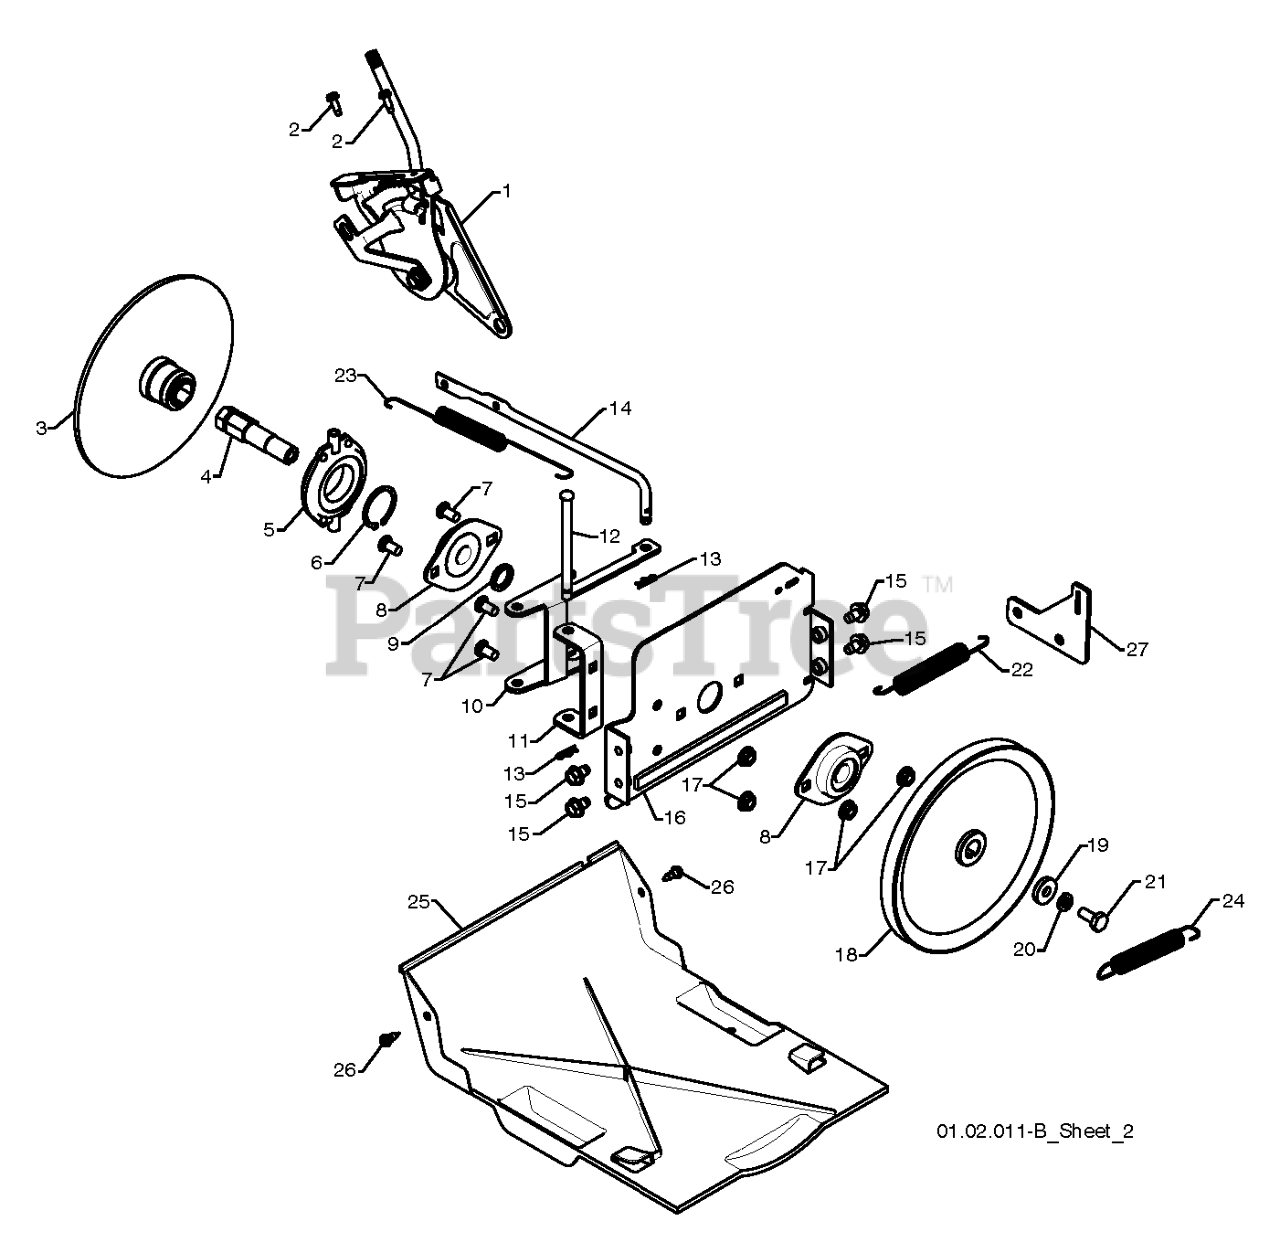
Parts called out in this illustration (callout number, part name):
1	HEAD ASSY SPEED
2	SCREW #10-24 X 5/8
3	DRIVE PLATE WELDMENT
4	SHAFT.HEX.SHORT
5	TRUNNION BEARING ASSY
6	RETAINING RING (2 2)(3 2)
7	BOLT
8	BEARING FLANGE
9	SPACER, BEARING
10	LEVER.SHIFTER.PLATE.BLACK
11	BRACKET.SHIFTER.SUPPORT.BLACK
12	PIN, PIVOT LEVER
13	RETAINER CLIP PM
14	ROD.CLUTCH.YELLOW.ZINC(VT)
15	Screw 5/16-18 x 1/2 Hex, Self Tapping 5/16-18 x 1/2
16	PLATE.DRIVE.MOUNT.BLACK
17	NUT.FLANGE.5/16
18	PULLEY.TRACTION.7.75
19	WASHER, FLAT
20	WASHER.LOCK.HVY.HLCL.SPR.5/16
21	Screw, Hex Head 5/16-18 x 3/4
22	SPRING.TRACTION.IDLER
23	SPRING.RETURN
24	SPRING, BRAKE
25	PAN.BOTTOM.PLASTIC
26	SCREW, HEX HEAD, TAPPING
27	BRACKET.TRACTION.SPRIN
